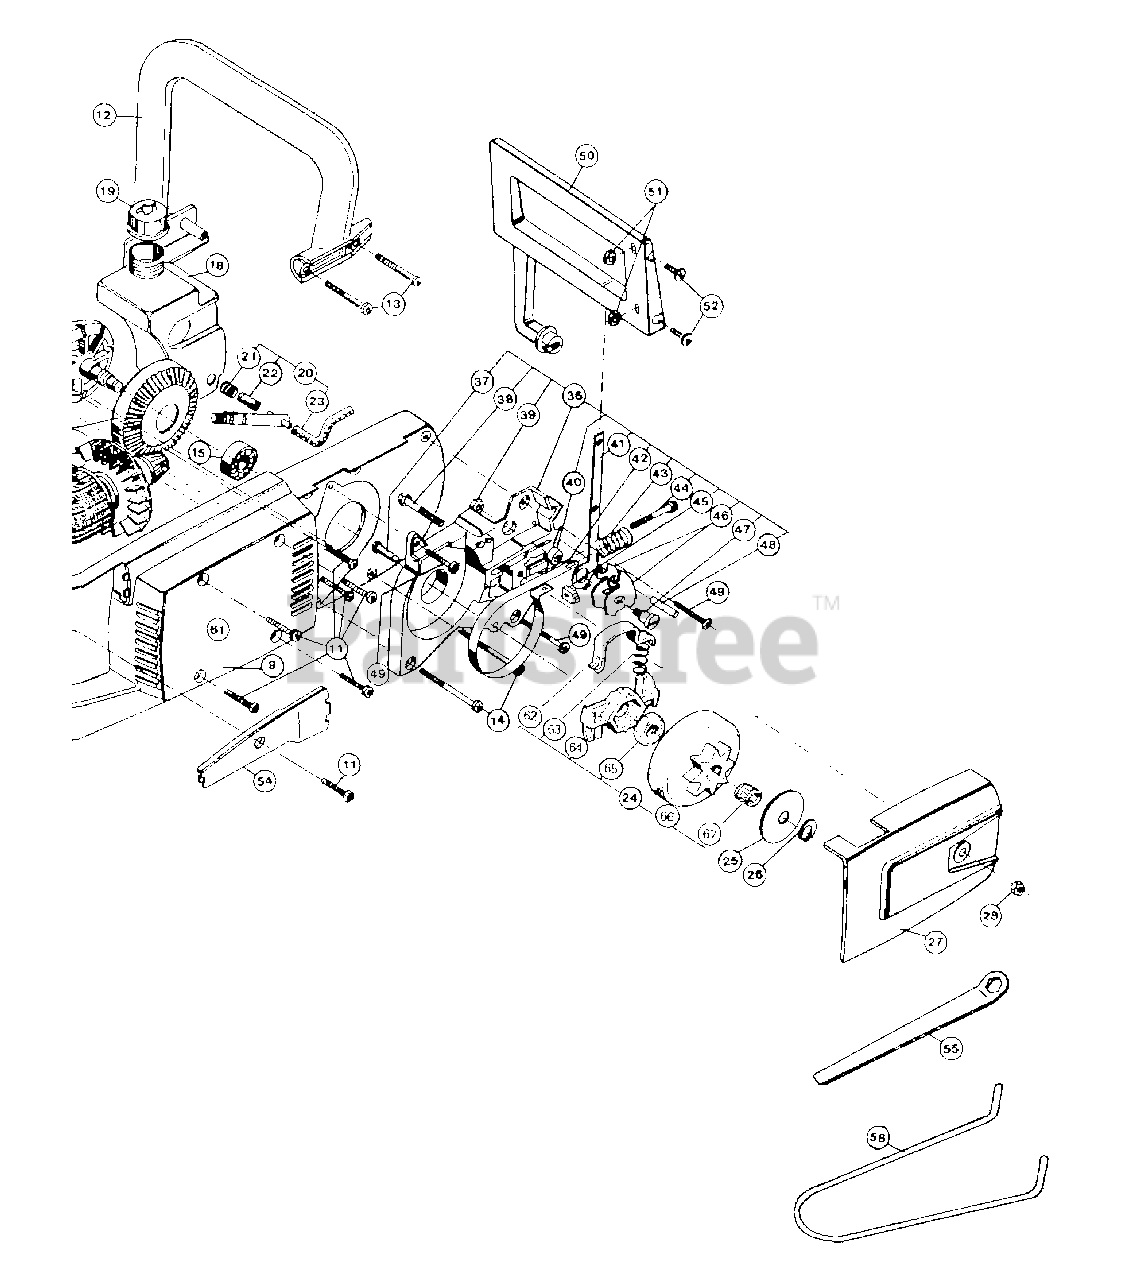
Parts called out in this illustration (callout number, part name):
45	CHAIN TENSIONER
46	RELEASE WASHER
48	SPIRAL PIN 4X16
50	HAND GUARD
52	SCREW MRX 5X12
53	BAR COVER
56	HOOK WRENCH
60	WARNING LABEL N
61	DECAL NLA
5080385-06	WARNING LABEL ENGLISH NLA
5080385-12	WARNING LABEL D.
